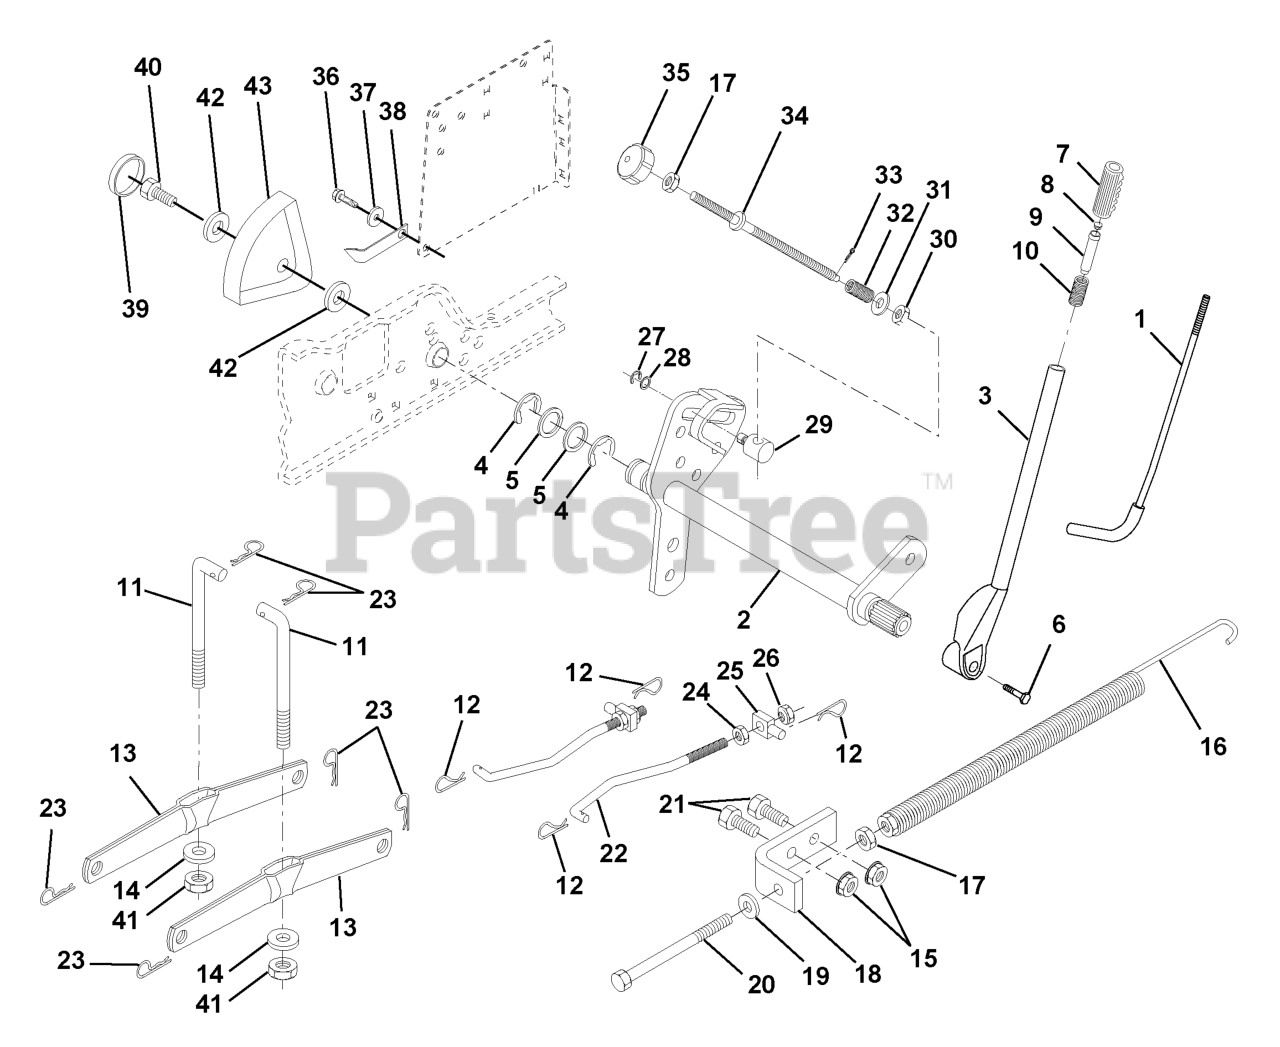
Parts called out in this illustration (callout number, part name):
1	LEVER ROD LT
2	SHAFT ASM, LIFT VGT
3	LIFT LEVER KIT
5	Washer 29/32 x 1-1/4 x 16 Ga.
6	BOLT
7	GRIP HANDLE
8	PLUNGER BUT KIT
9	PLUNGER BUT KIT
10	SPRING**
11	LINK LIFT
12	SPRING RETAINER
13	ARM.REAR.SUSPENSION
14	BEARING PIVOT
16	LIFT SPRING
17	NUT
19	WASHER
21	BOLT
22	FRONT LINK
23	RETAINER-SPRNG RB
24	NUT.HEX.JAM.1/2-13
25	TRUNION
26	NUT.LK.W/WSH.1/2.
27	Ring, Klip #T5304-37
28	Washer 15/32 x 3/4 x 16 Ga.
29	TRUNION LT
32	SPRING.COMP.INF.H
33	COTTER PIN
34	ROD.LIFT.ADJUSTABLE
35	KNOB INF 3/8-16
36	SCREW
38	POINTER HGT
40	SCREW.THDROL.5/16-18X3/4.TTY
41	NUT CROWNLOCK 3/8-24
43	HEIGHT INDICATOR
